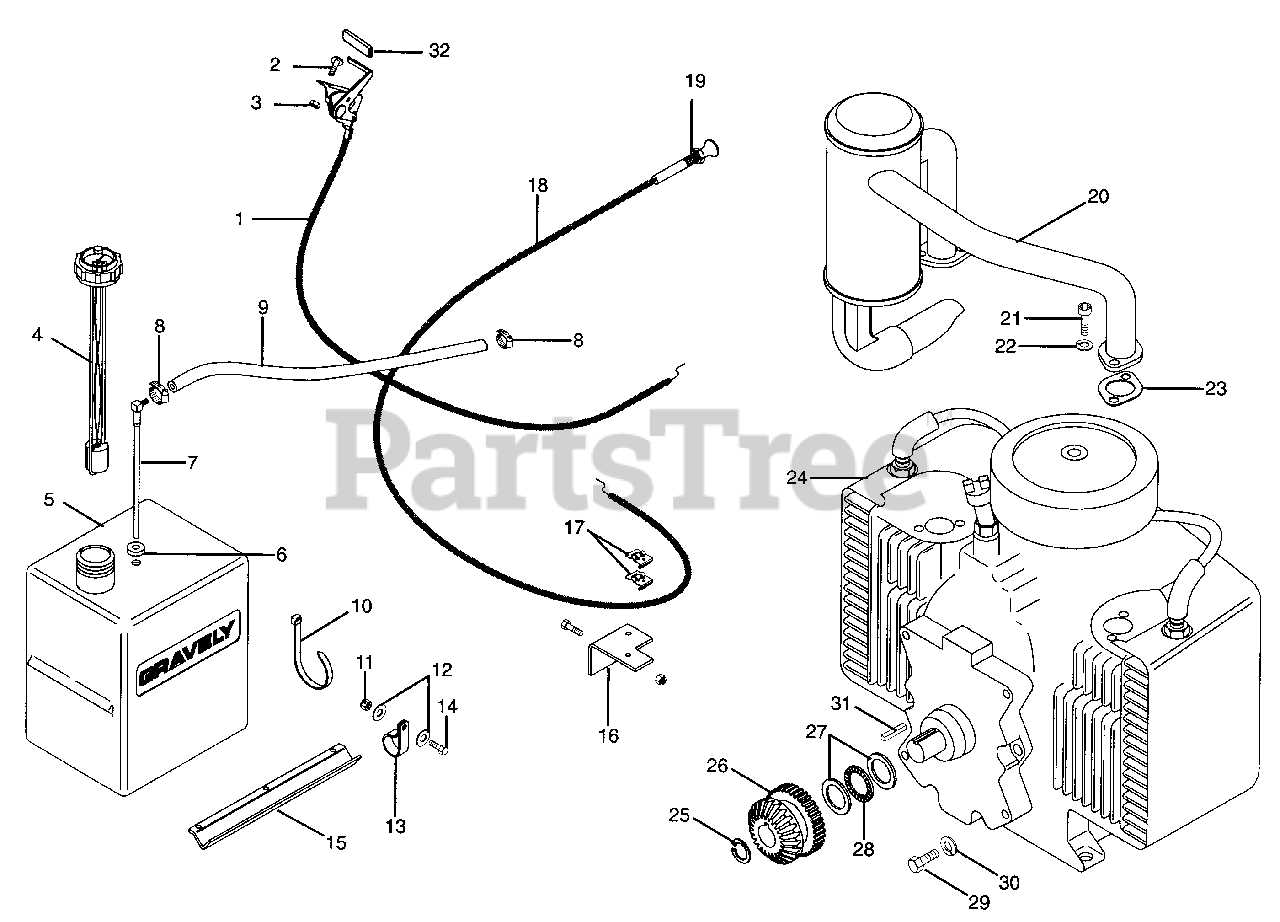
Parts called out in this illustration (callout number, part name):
1	Throttle Cable
2	Screw-Machine 10-24 x .50
3	Nut-Locking- Nylon -10-24
4	Gauge-Fuel
5	Tank-Fuel
6	Bushing
7	Fitting-Tank
8	Hose Clamp
9	Gas Line-Bulk
10	Tie-Cable
11	Nut-Locking-Center .312-18
12	Washer-Flat-Steel .344 x .688 x .065
13	Cable Clamp
14	Bolt-Hex .31-18 x 1.00 Grade 5
15	Shield-Heat
16	Bracket-Throttle & Choke
17	Clip-Speed
18	Control-Choke
19	Nut-Jam .375-24
20	Muffler-Exhaust
21	Screw-Cap .31-18 x .75
22	Washer-Lock .313 x .078
23	Gasket-Exhaust
24	Engine 16 HP Magnum PS-24633 (066,067)
24	Engine 18 HP Magnum PS-24590 (068)
24	Engine 20 Hp S.B. Kohler PS-49562 (069)
25	Ring-Retaining 1.249 x .050
26	Gear-Spur & Bevel
27	Washer-Thrust 1.125 x 1.750 x .123
28	Bearing-N-Thrust 1.84 x 1.127 x .078
29	Bolt-Hex .50-13 x 1.75
30	Washer-Lock .50 x .125 Reg
31	Key-Square .248 x 1.25 x .248
32	Grip
